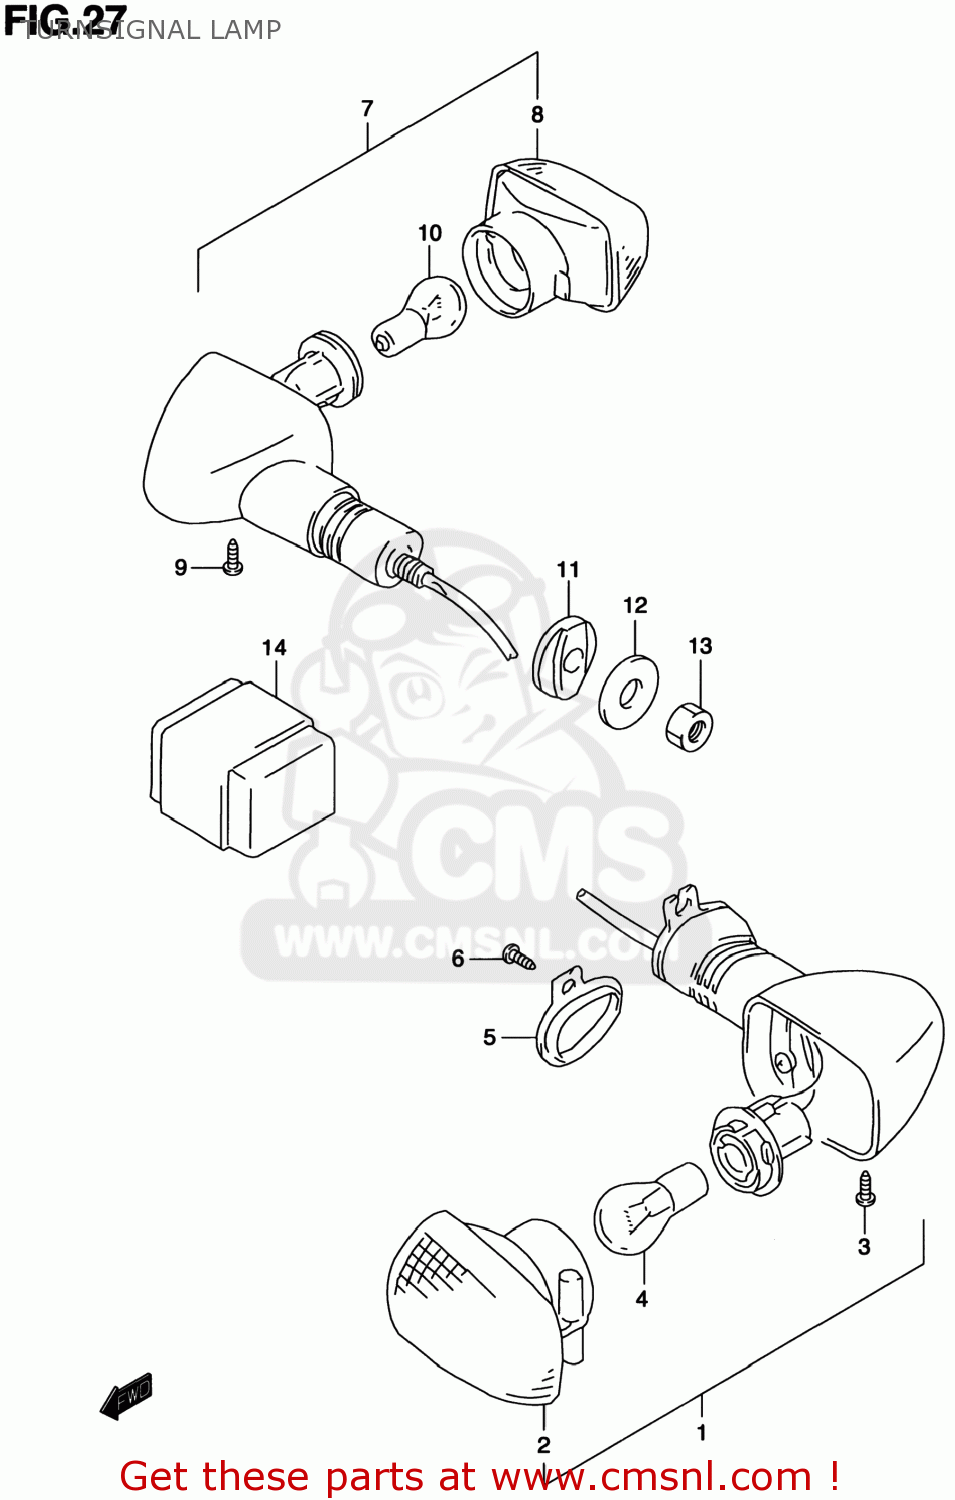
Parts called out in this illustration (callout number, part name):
1	LAMP ASSY,FR TURN SIGNAL,R
2	LAMP UNIT
3	SCREW
4	BULB(12V21W)
5	PLATE,FR TURNSIGNAL LAMP
6	SCREW
7	LAMP ASSY,RR TURNSIGNAL,R
8	LAMP UNIT
9	SCREW
10	BULB(12V21W)
11	SPACER,RR TURNSIGNAL
12	WASHER(10.5X30X2.3)
13	NUT
14	RELAY ASSY
